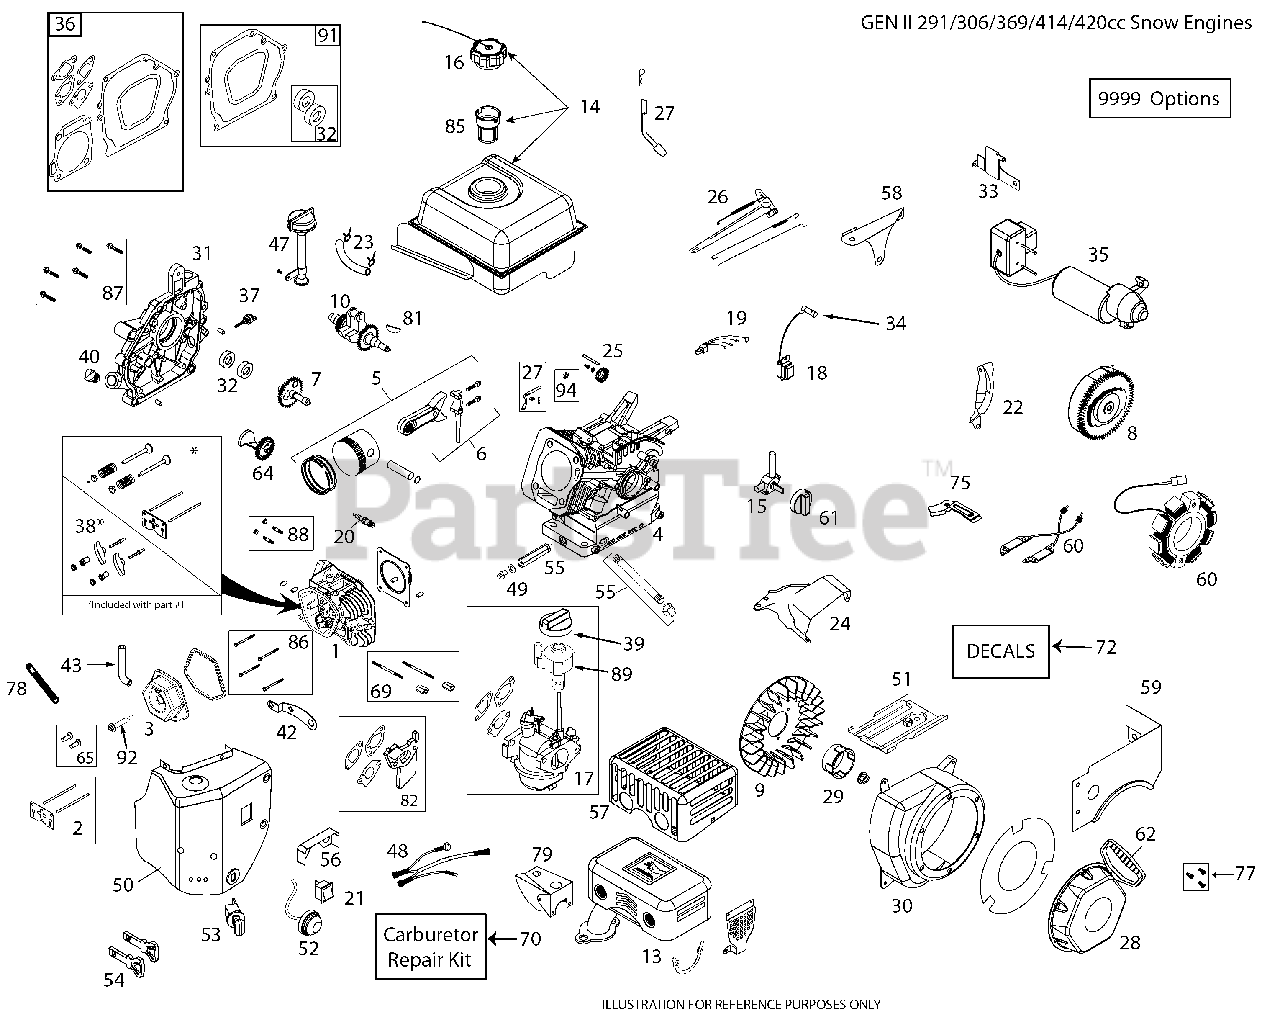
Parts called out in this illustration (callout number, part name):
1	CYLINDER HEAD LCT 178 INCLUDES
2	PUSH ROD TAPPET KIT
3	VALVE.COVER.LCT.414CC.
4	CYLINDER LCT 369 SKSN3333.1
5	PISTON.AND.ROD.ASSY(SK4141400)
6	CONNECTING ROD ASSEMBLY
7	CAMSHAFT(SK4141600)
8	FLYWHEEL.EL.ST.SKSN4408.1
9	FLYWHEEL.FAN(SK4144000)
10	CRANKSHAFT KEYED #18 LCT 414C
13	MUFFLER ASSY LCT SNO
14	FUEL.TANK.ASSY.SNOW(SKSN4300)
15	FUEL.PETCOCK.SNOW(SKSN4900)
16	FUEL.TANK.CAP.SNOW(SKSN4301)
17	CARBURETTOR L18D LCT 369
18	IGNITION.COIL.(CDI).291-414CC
20	SPARK.PLUG(SK2911550)
21	ON/OFF.SWITCH.SNOW(SKSN4403)
22	SHIELD.U/FYWHL.CHARG(SKSN4604)
23	FUEL HOSE KIT
24	RP TOP SHIELD
25	GOVERNOR.GEAR.ASSY(SK4142900)
26	GOVERNOR.ARM.ASSY(SKSN4502)
27	GOVERNOR.SHAFT(SK4143100)
28	RECOIL.START.ASSY.SNW(SKSN4600
29	STARTER.CUP.SML.SNOW(SKSN4601)
30	BLOWER HOUSING.LCT 369 GLOSS
31	CRANKCASE.COVER.LCT.414CC.HIGH
32	OIL SEAL KIT NON-GENERATOR
33	ELECTRIC.START.BRKT(SKSN4405)
34	SPARK.PLUG.BOOT.SNW,SKSN4691.1
35	ELEC.START.ASSY.SNOW(SKSN4400)
36	GASKET KIT ENGINE LCT 369
37	DIPSTK.OIL.BLK.LCTSK4143711.1
38	ROCKER ARM KIT
39	CHOKE.KNOW.SNOW(SKSN4500)
40	NONREMVABLE.OIL.PLUG(SK4143715
42	CDI.BOX.BRKT.SNOW(SKSN4402)
43	BREATHER TUBE LCT 291/369/414
47	HIGHOIL.FILL.ASSY.KIT(SKSN4911
48	WIRE.HARNESS(SKSN4406)
49	OIL.DRAIN.PLUG
50	BOX HEATER ASM 414 LCT
51	SHIELD.CYLINDER.SNOW(SK4141010
52	PRIMER.BULB.ASSY(SKSN4304)
53	KEY.SWITCH.ASSY.SNOW(SKSN4401)
54	KEY SET(2 KEYS) SKSN0407.1
55	OIL PIPE DRAIN EXTENDED.LCT SK
56	SHIELD.VAPOR(SKSN4606)
57	MUFFLER (SKSN2210.1)
58	PLATE.GOVERN.LINK.S
59	SKIRT FUEL TANK
60	ALTERN.60WATT.SKSN2402.1
61	FUEL KNOB-SNOW
62	HANDLE.RECOIL.DELUXE.LCT
64	COUNTER WEIGHT KIT
65	TAPPET KIT.LCT.SK2911005.1
69	STUD.CARB.MOUTING.KIT.414CC
70	CARBURETTOR REPAIR KIT 291CC/4
77	BOLT.KIT.RECOIL.LCT.ALL.ENGINE
78	STRAP.RETAINING.TUBE.BREATHER.
79	SHIELD CARBURRETOR COVER 414
81	KEYS.FLYWHEEL.208/414CC.5PACK
82	SPACER.CARBURETOR.414CC.LCT
86	KIT.BOLT.CYLINDER.HEAD.(4PC)
87	KIT.BOLT.CRANKCASE.COVER.414CC
88	STUD.MUFFLER.KIT.LCT
89	KNOB LCT.SKSN5325.1 SPEED
91	GASKET KIT CRANKSHAFT.LCT
92	CENTER VALVE COVER BOLT
94	SEAL GOVERNOR SHAFT OIL.LCT
9999	HIGH ALTITUDE JET 6000FT
9999	KIT.BOLT.LCT.SK9990.1
